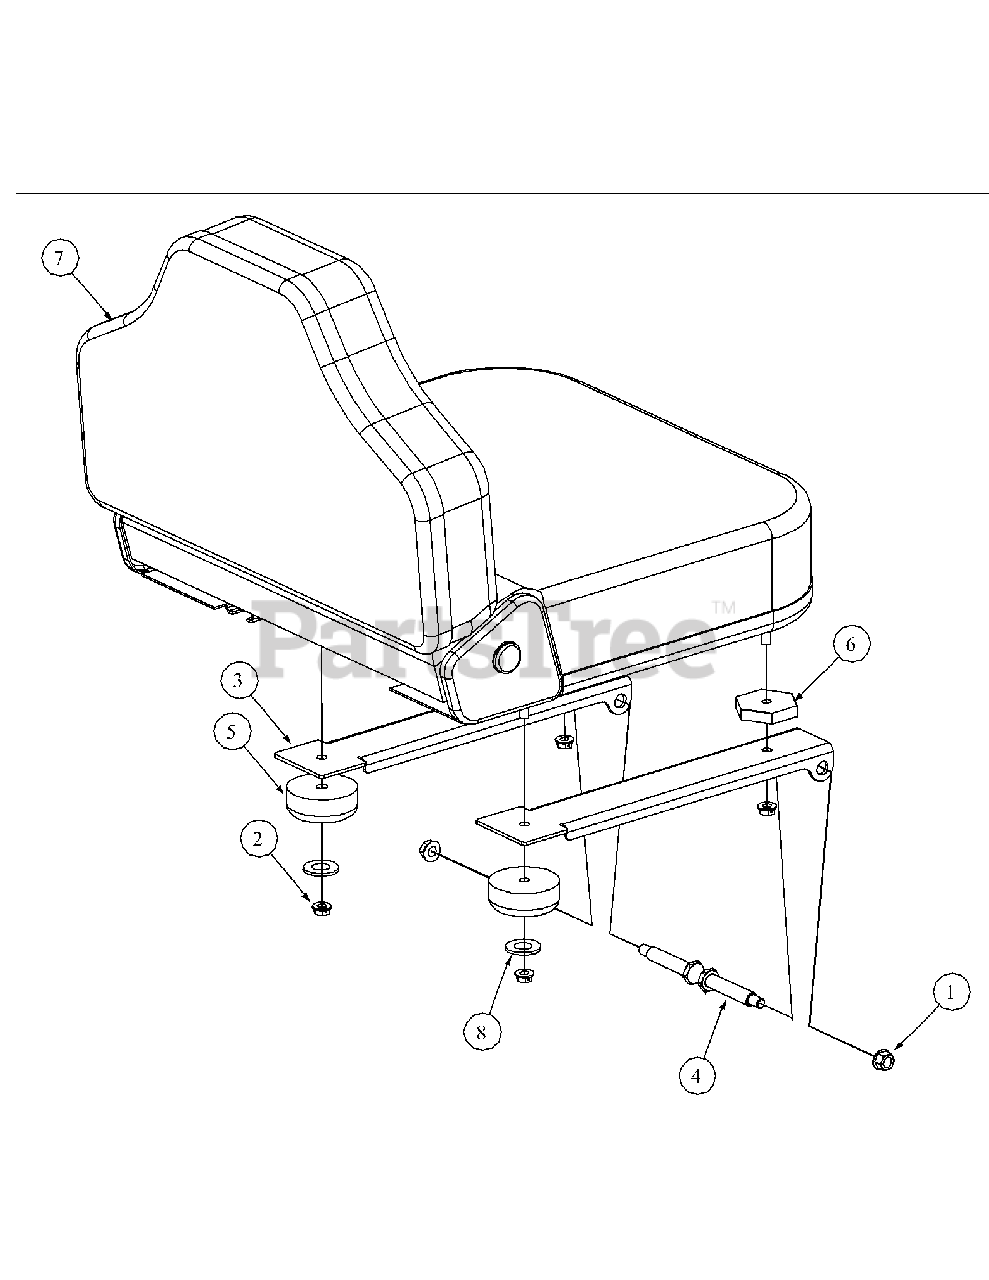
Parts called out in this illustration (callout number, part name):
1	Nut, Hex 3/8-16 Flange Lock
2	Lock Nut, Hex Flange, 5/16-18
3	Mounting Bracket, Seat
4	Shoulder Screw, .50 x 2.345, 3/8-16
5	Grommet, 2.5 OD x 1.0 Long
6	Spacer, 2.0 Hex x .41 Lg
7	Adjustable Seat, Grey
8	Flat Washer, .406 ID, 1.00 OD, .105
